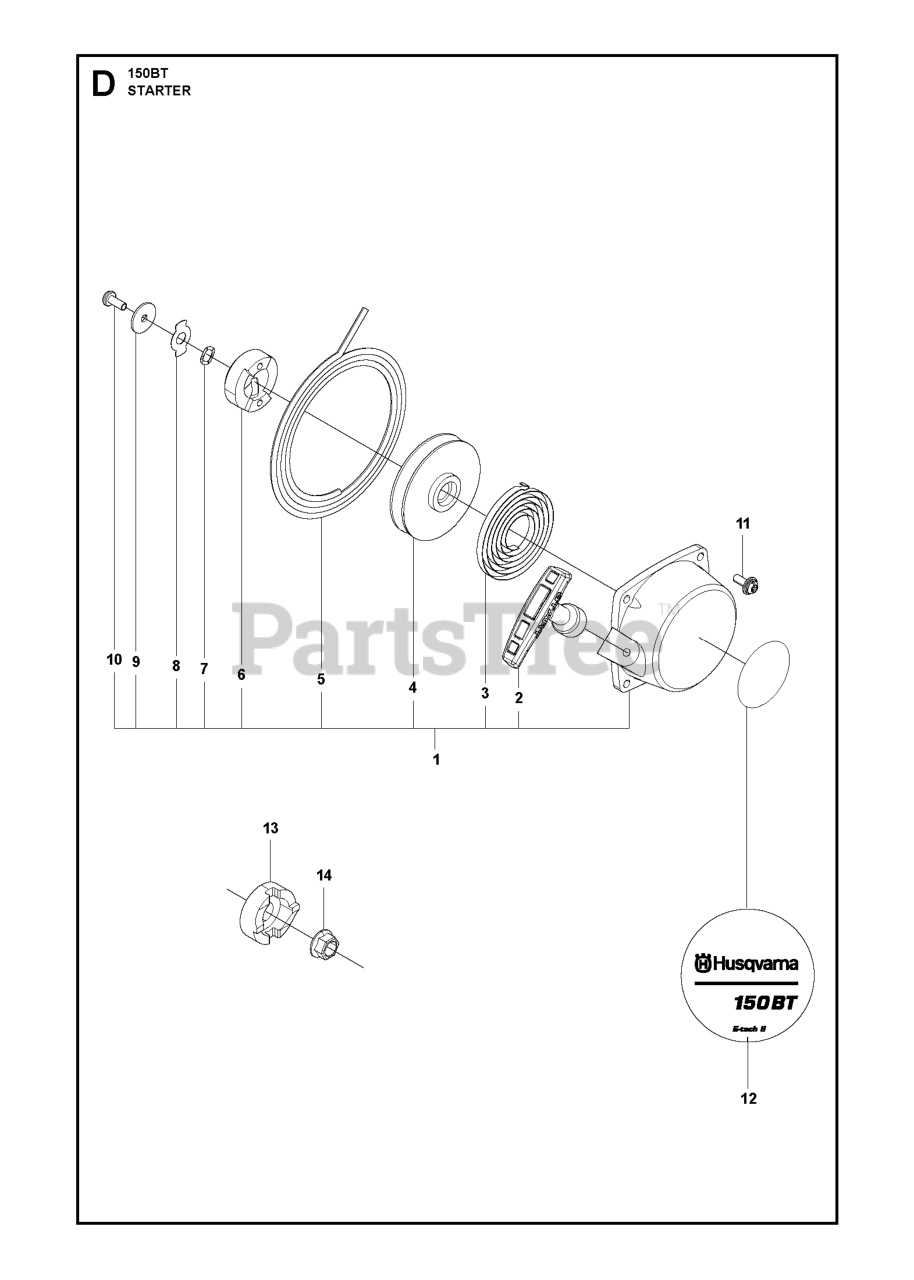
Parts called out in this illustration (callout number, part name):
1	STARTER ASSY
4	STARTER PULLEY
5	STARTER ROPE
6	STARTER PAWL
8	RETAINER
9	WASHER
11	SCREW, T27
12	LABEL RECOIL
